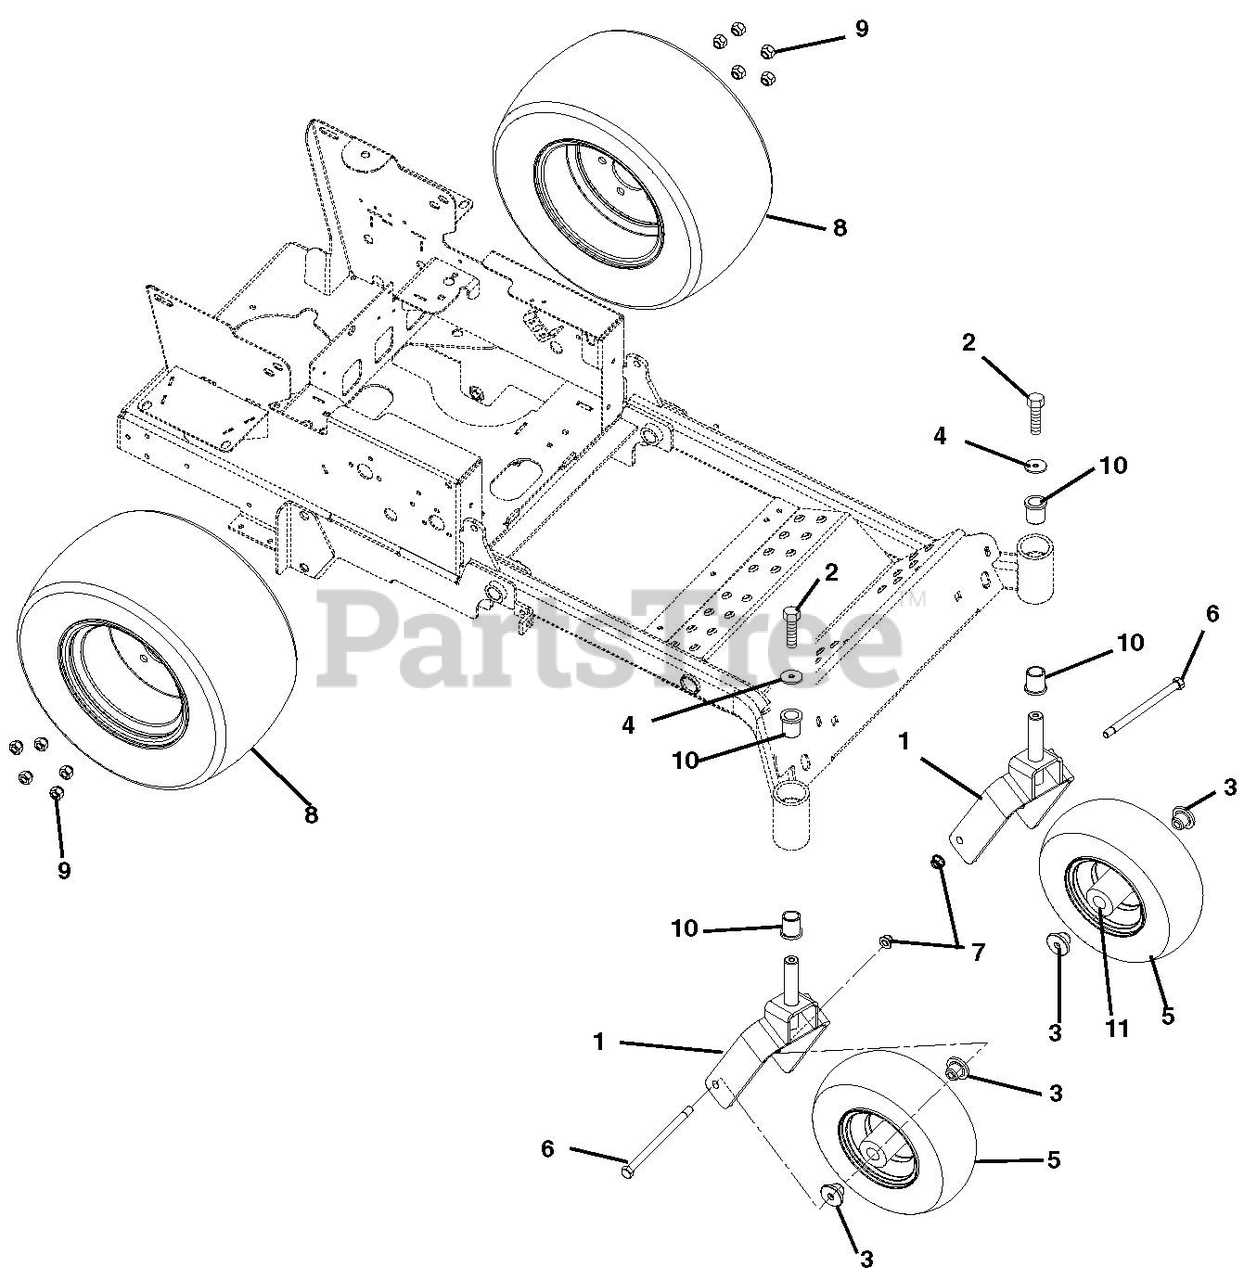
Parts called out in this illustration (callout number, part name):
1	WMT, CASTER FORK (HD)
2	BLT-HEX .38-16X1.0 GR8 YZ EP30
3	SPACER, FRONT WHEEL
4	WSHR-FL-STL .380X1.50X.125YWZC
5	TIRE/WHEEL ASSY, 13X5.00-6
5	TIRE, 13X5.00-6
6	@BLT-HEX .50-13X7.50 GR5 YWZC
7	@NUT-LK-NYL-FLG .50-13 YWZC
8	TIRE/WHEEL ASSY, 20X10.00-10
8	TIRE, 20X10.00-10
9	WHEEL NUT .500-20 YZ
10	BSHG-FLG 1.00X1.25X1.50X1.50EP
11	BRG, 25MM ID X 52MM OD X 15MM
